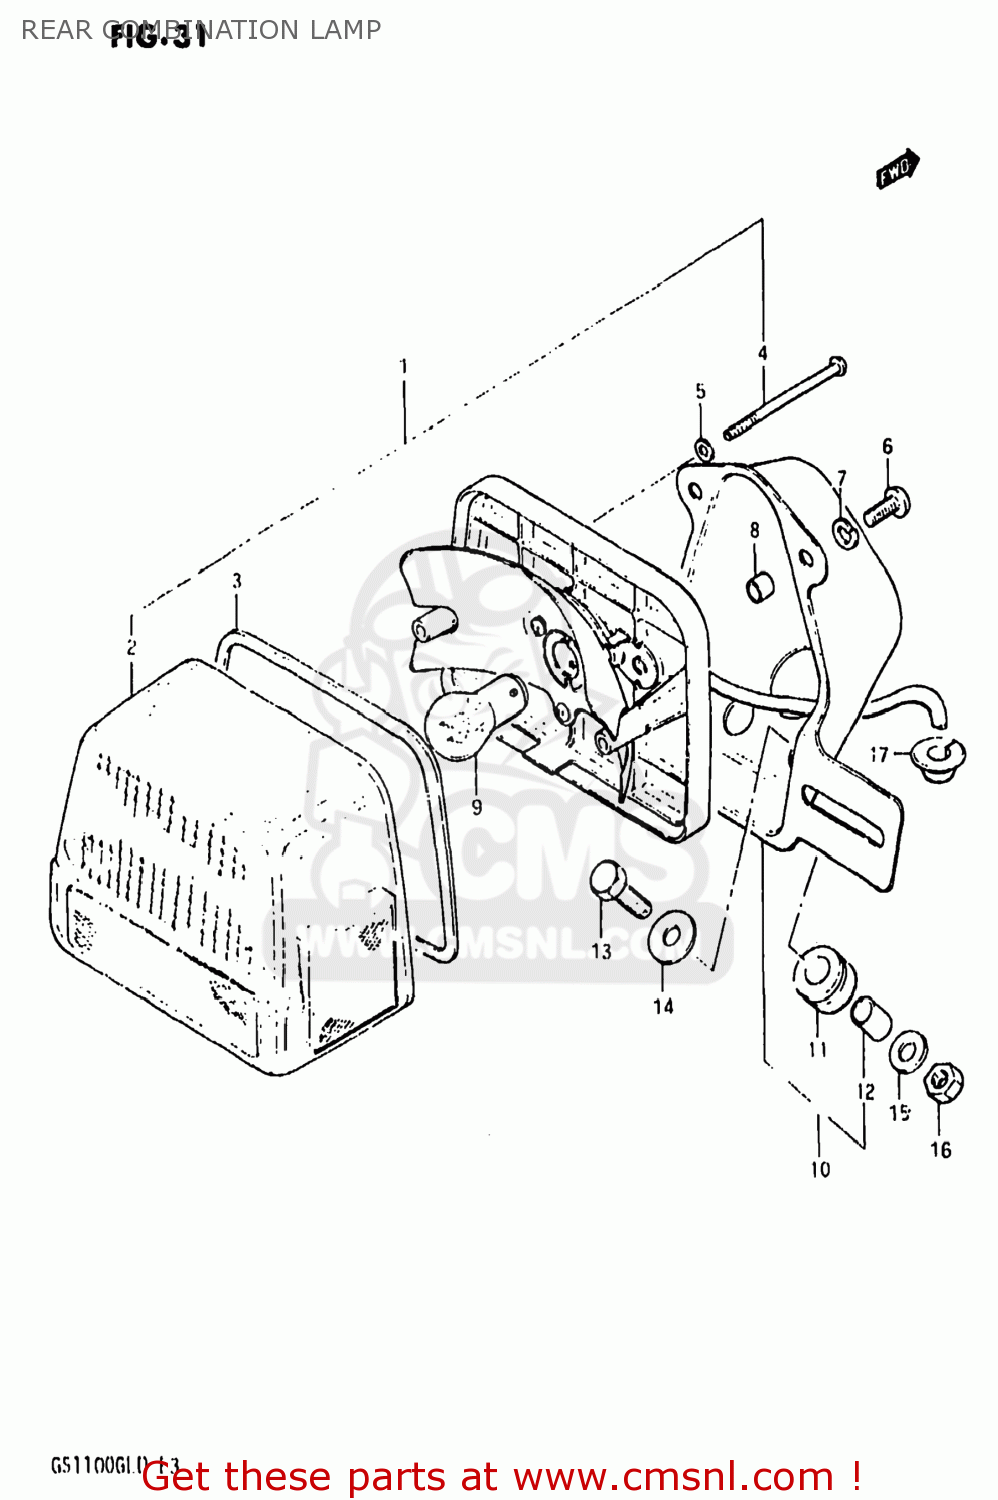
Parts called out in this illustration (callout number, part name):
1	LAMP UNIT,RR COMBNATION
2	LENS
3	GASKET (NAS)
4	SCREW
5	GASKET (NAS)
6	SCREW
7	LOCK WASHER
8	SPACER
9	BULB(12V23W)
10	BRACKET UNIT,TAIL LAMP
11	CUSHION
12	SPACER
13	BOLT
14	WASHER (6.5X20X1.2)
15	WASHER
16	NUT
17	GROMMET
